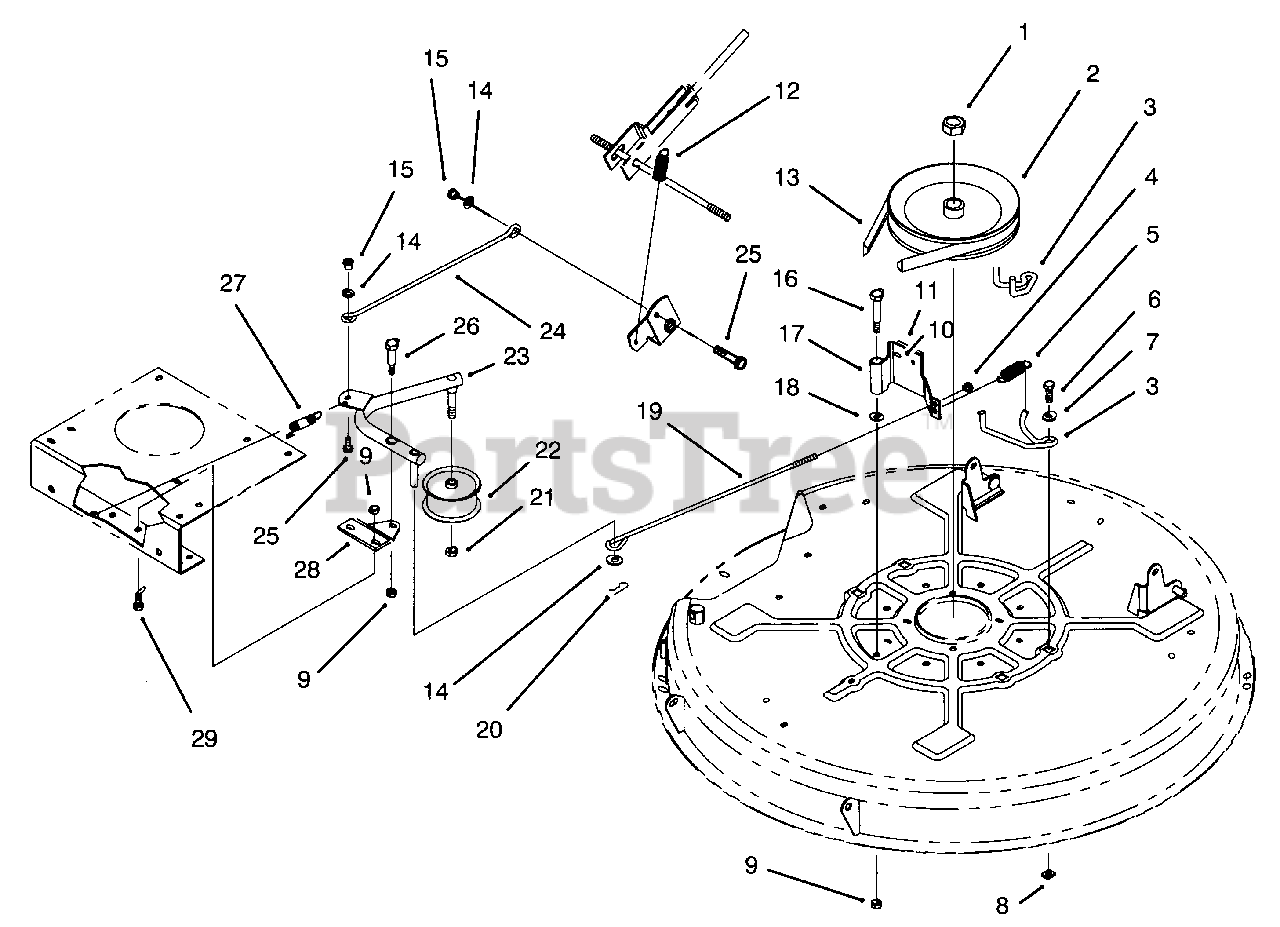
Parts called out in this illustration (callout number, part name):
1	Nut-Lock
2	Pulley-Deck
3	Guide-Belt
4	Nut-Lock
5	Spring-Extension
6	Screw-Hex Hd. Cap
7	Washer-Fender
8	Nut-Retained
9	Nut-Lock
10	Rivet-Pop
11	Pad-Brake
12	Spring/Cable Assembly
14	Washer-Flat
16	Bolt-Shoulder
17	Deck Brake Assembly (Incl. Ref. #10 & 11)
18	Washer-Flat
19	Rod-Deck Brake
20	Pin-Hair Cotter
21	Nut-Lock
22	Pulley-Idler
23	Arm-Idler
24	Rod-Deck Engage
25	Screw-Hex Flange Hd.
26	Bolt-Shoulder
27	Spring-Extension
28	Plate-Idler Mount
29	Screw-Hex Hd. Can
